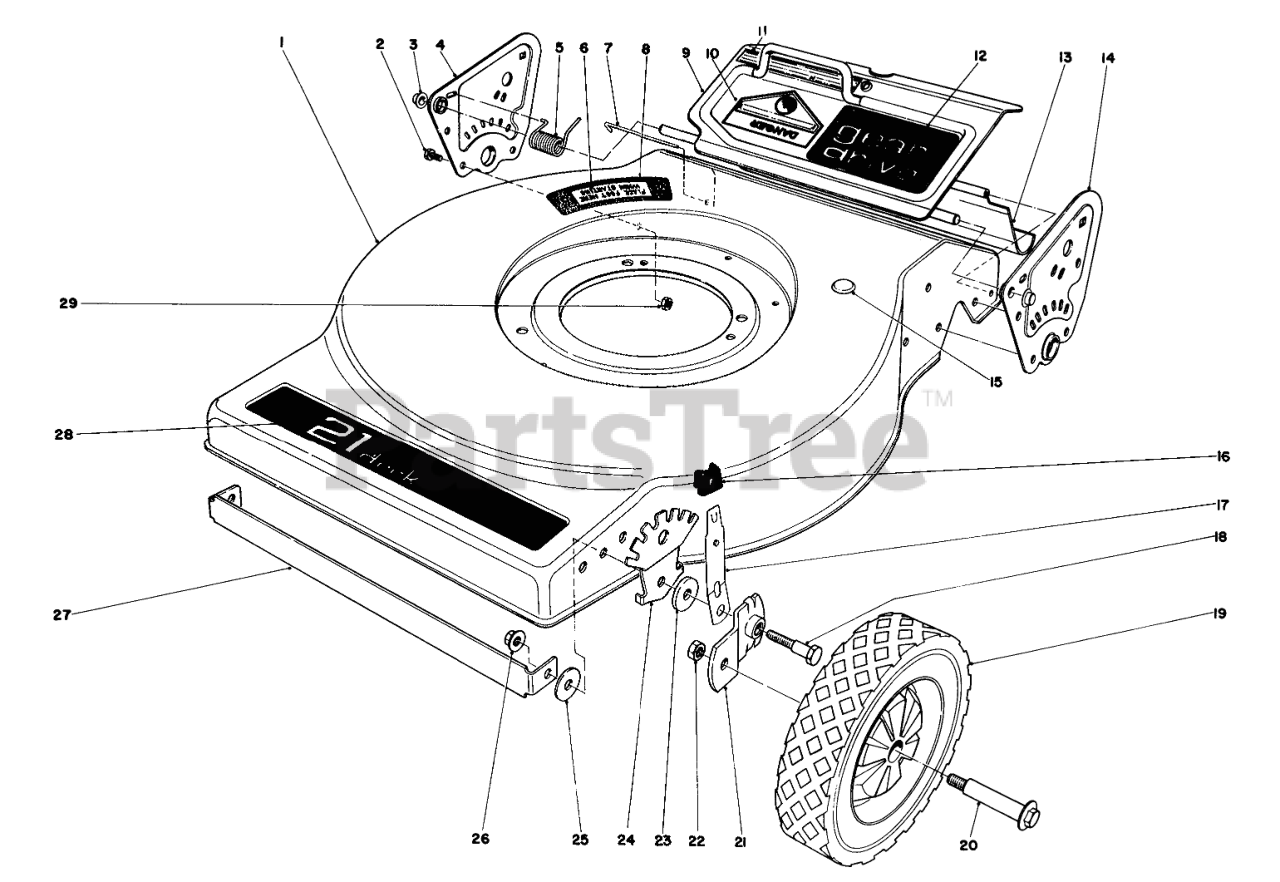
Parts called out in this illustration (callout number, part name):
1	Housing
2	SCREW-HH
3	RETAINER-PUSH ON
4	Side Plate R.H
5	TORSION SPRING
6	Decal Step Pad
7	SHIELD ROD
8	PAD STEP
9	Rear Door
10	DECAL-DANGER
11	Decal-Door
12	Decal-Door
13	SAF SHIELD REAR
14	Side Plate L.H.
16	KNOB-ARM
17	SPRING ARM ASM
18	PIVOT SCREW
19	WHEEL TIRE ASM 8 IN
20	BOLT-WHEEL
21	PIVOT ARM ASM A
22	Nut
23	PIVOT WASHER
24	Quadrant
25	WASHER
27	DECK SUPPORT
28	Decal-Deck
29	NUT-LOCK, CONE
